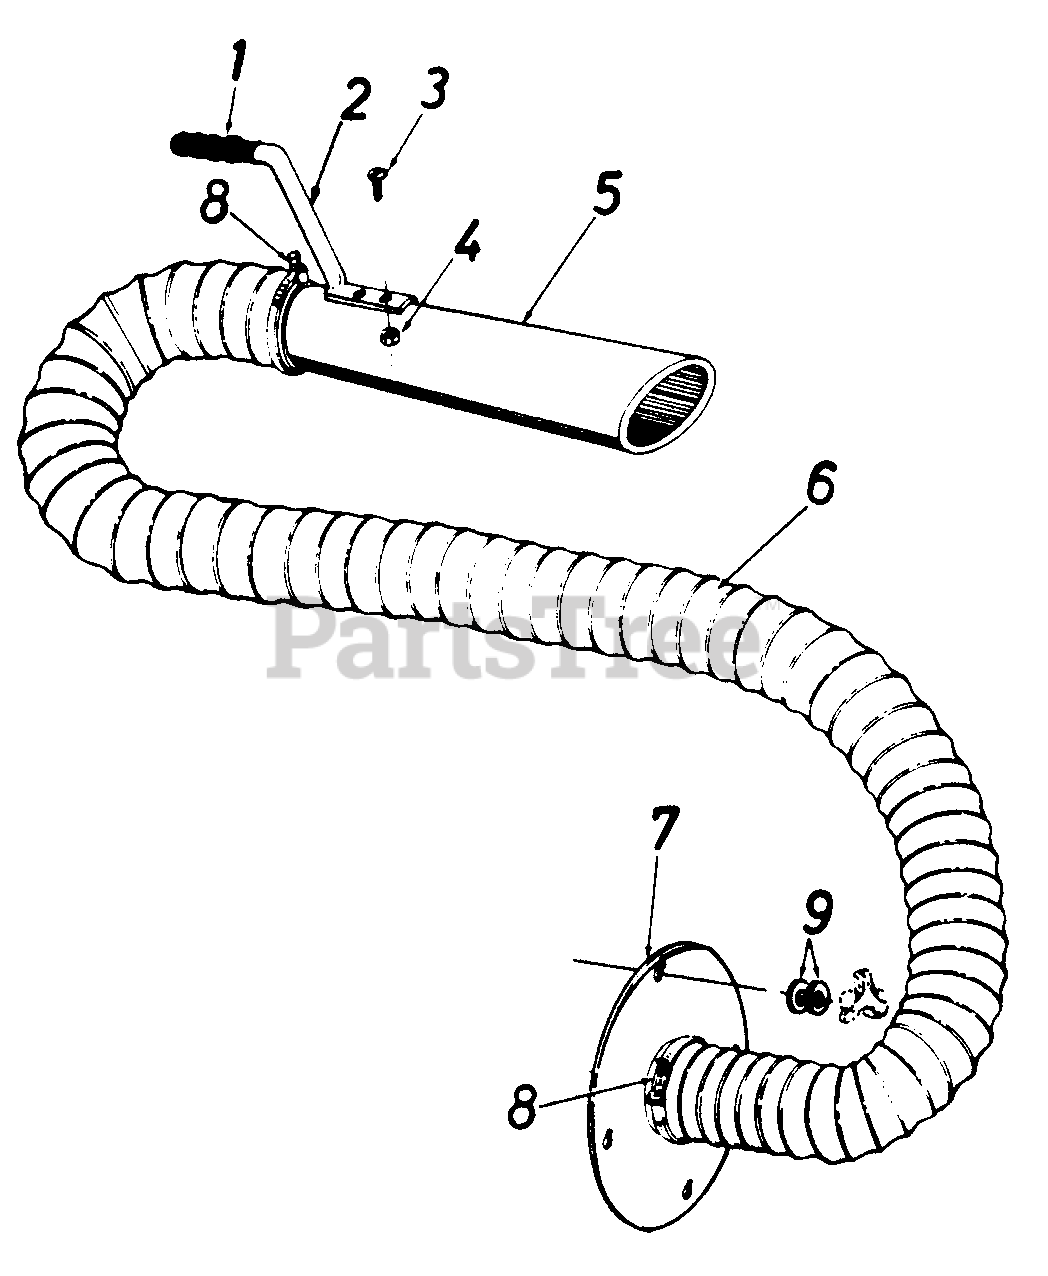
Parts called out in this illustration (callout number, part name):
1	Handle Grip
2	Handle
3	Truss Sems Scr. 10-24 x 1/2" Lg.
4	Hex Nut 10-24 Thd.
5	Hose Nozzle
6	Flexible Hose 4" Dia. x 10" Lg.
9	Flat Washer .34 I.D. x 1.12 O.D.
